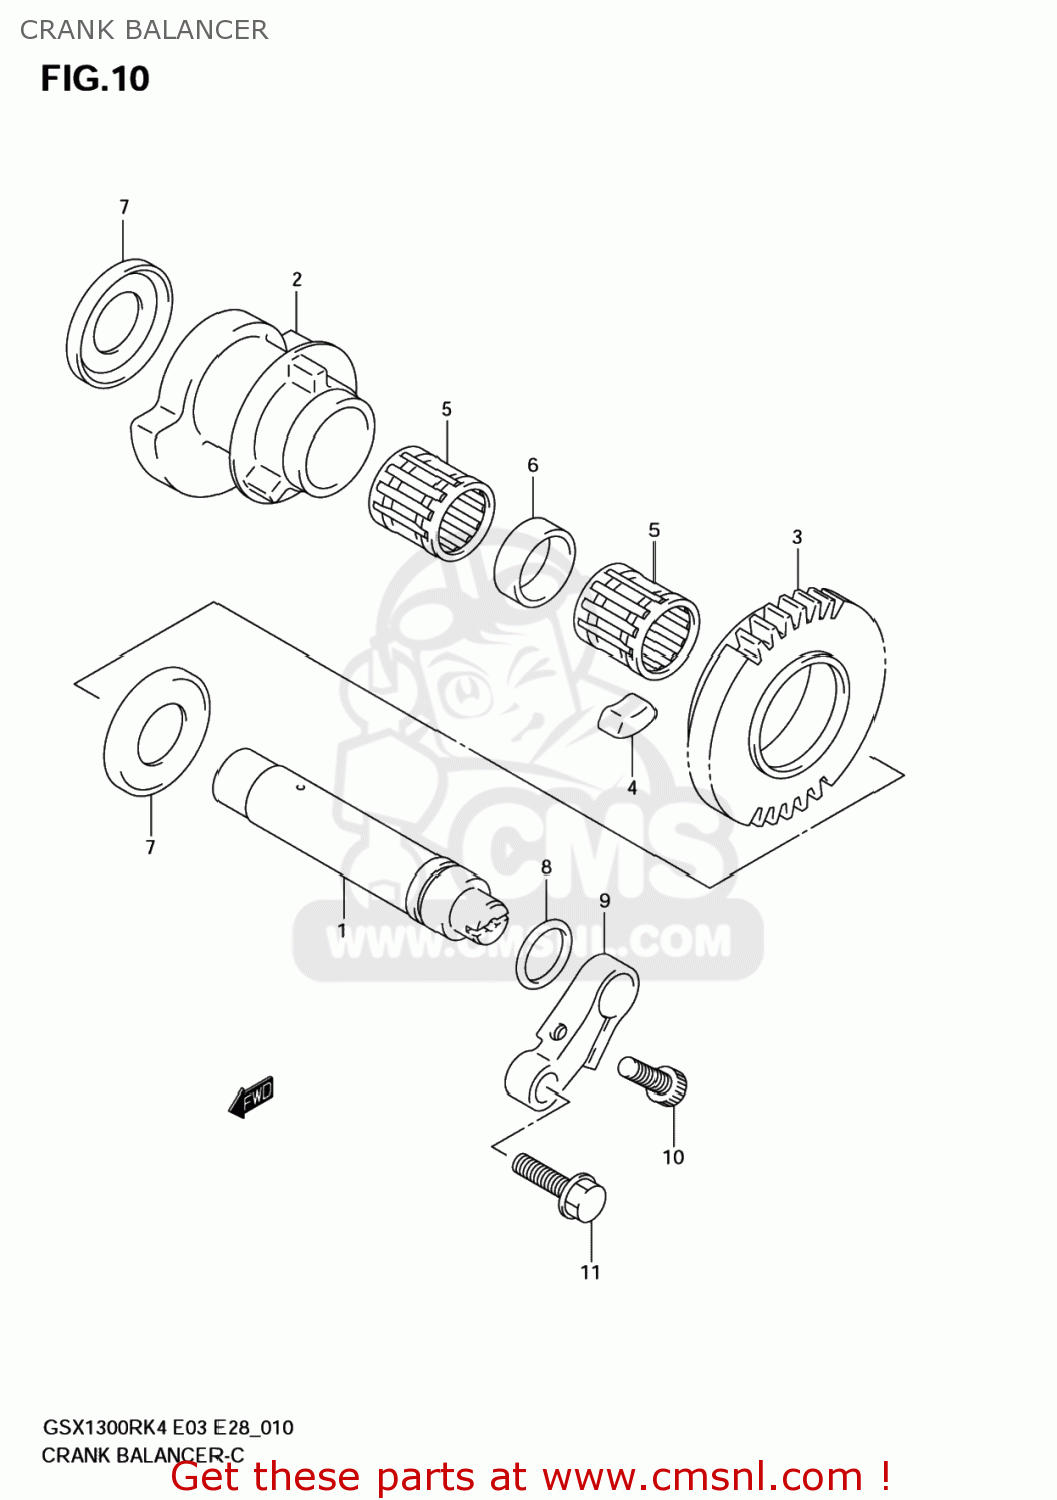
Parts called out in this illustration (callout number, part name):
1	SHAFT COMP,CRANK BALANCER
2	BALANCER,CRANK
3	GEAR,CRANK BALANCER
4	DAMPER,BALANCER GEAR
5	BEARING(19X26X25.2)
6	SPACER(19X26X8.6)
7	WASHER
8	O RING(D:1.9,ID:16.8)
9	ARM,BALANCER SHAFT
10	BOLT,CRKCASE,R
11	BOLT 6X20
